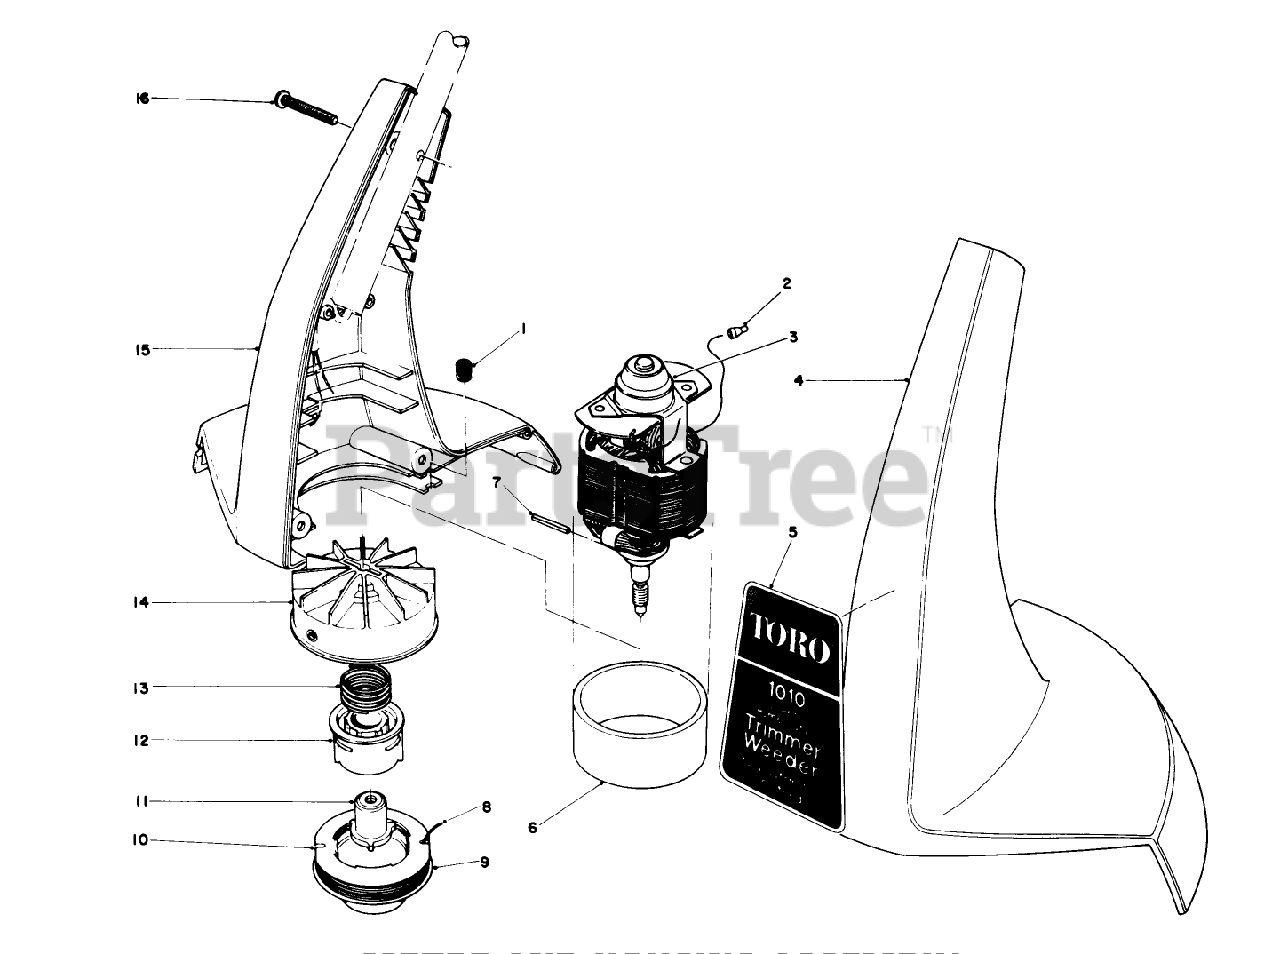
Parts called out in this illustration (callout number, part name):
7	COIL PIN
8	Line-Cutting (30- .05 Dia.)
9	SPOOL CAP
10	Prewound Spool Cap
11	DRIVER DETENT
12	CORE - SPOOL
13	SPRING-COMPRESSION
14	FAN HUB ASM
